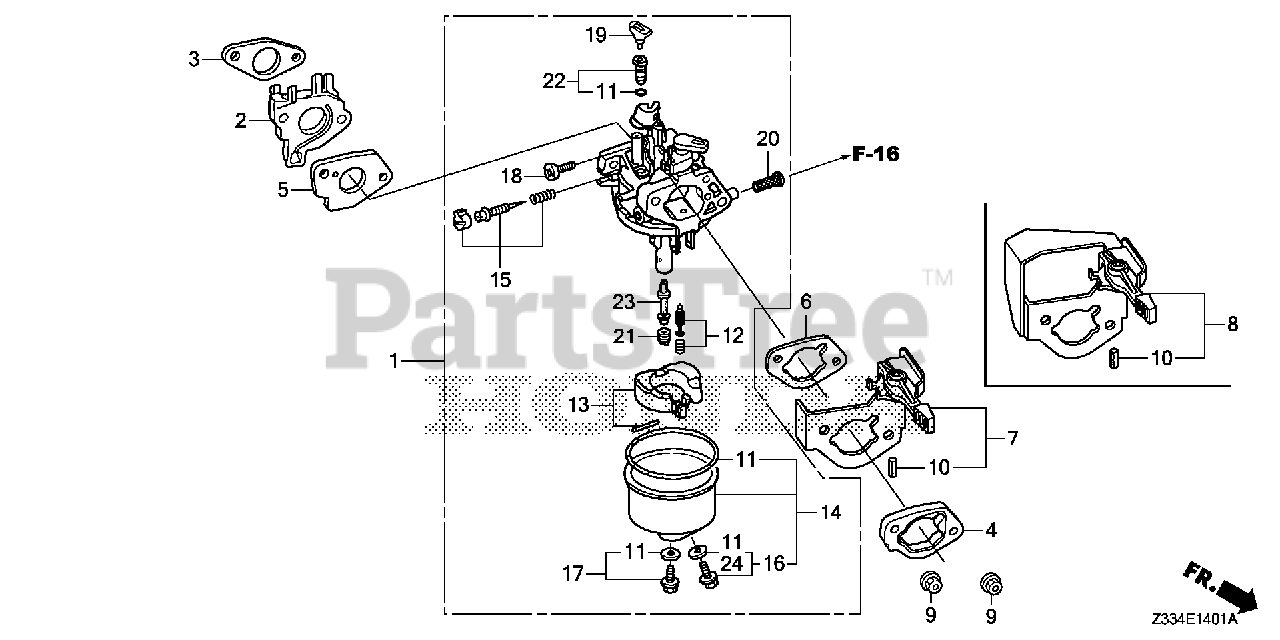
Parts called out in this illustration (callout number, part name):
1	CARBURETOR ASSY. (BE77Z A)
2	INSULATOR, CARBURETOR
3	GASKET, INSULATOR
4	SPACER, CARBURETOR
5	GASKET, CARBURETOR
6	GASKET, AIR CLEANER
7	BASE, CHOKE
9	NUT, FLANGE (6MM)
10	PIN, SPRING (2X12)
11	GASKET SET
12	VALVE SET, FLOAT
14	CHAMBER SET, FLOAT
15	SCREW SET, PILOT
16	SCREW SET, DRAIN
17	SCREW SET
18	SCREW, THROTTLE STOP
19	COLLAR, SETTING
20	SCREEN, FUEL STRAINER
21	JET, MAIN (#80)
21	JET, MAIN (#82)
21	JET, MAIN (#85)
22	JET SET, PILOT (#40)
23	NOZZLE, MAIN
24	WASHER, PLAIN (6.2X10.7 DRAIN)
